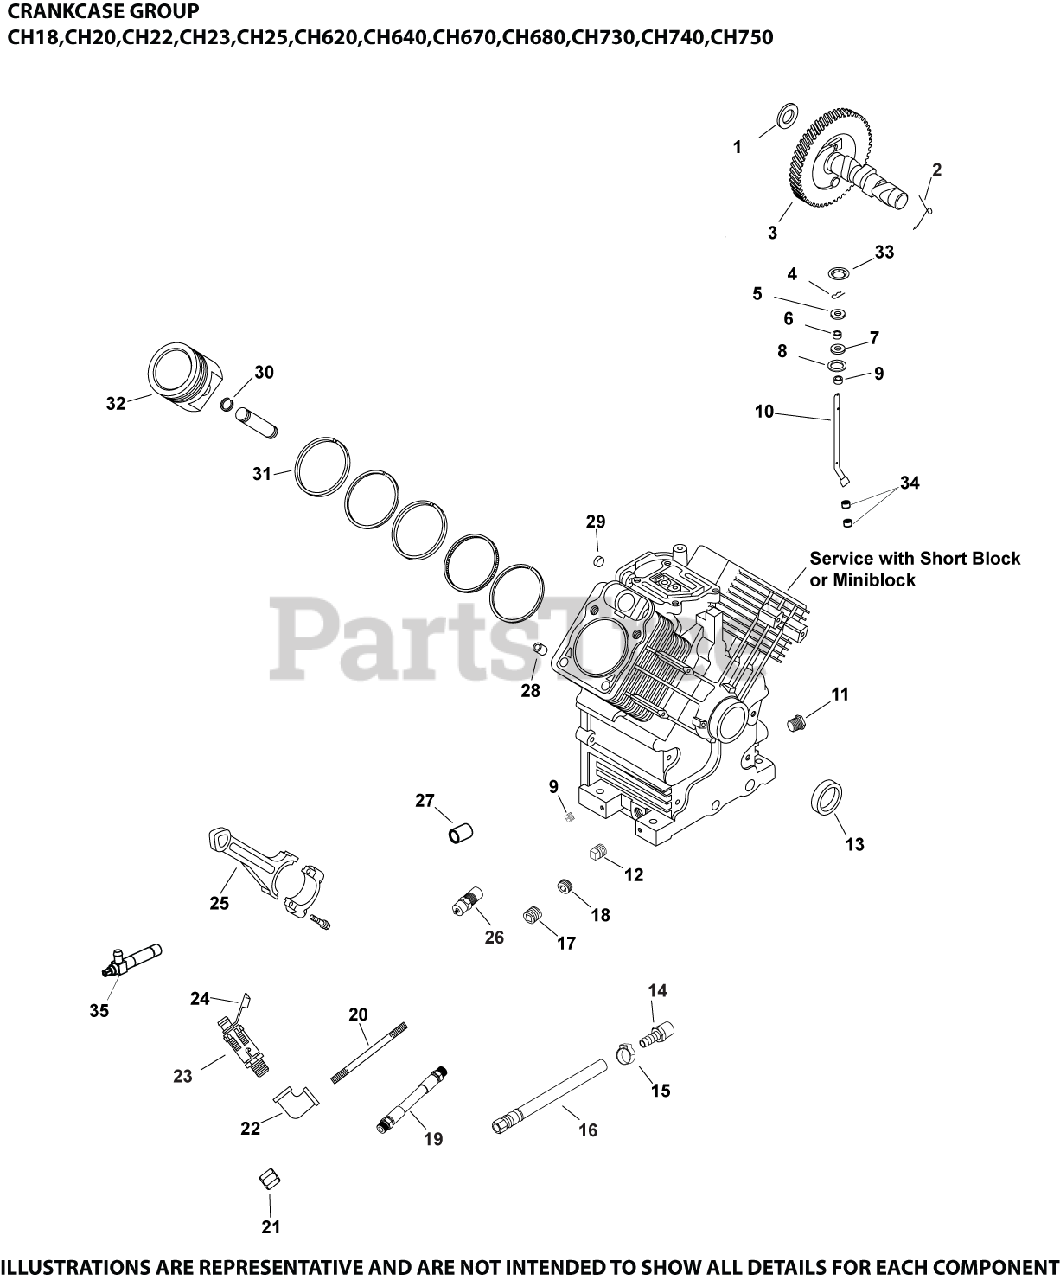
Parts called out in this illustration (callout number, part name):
3	KIT, CAMSHAFT
5	WASHER, FLAT 9 MM
7	SEAL, GOVERNOR CROSS SHAFT
10	SHAFT, GOVERNOR CROSS
12	PLUG, SQ HD PIPE 3/8"
13	SEAL, OIL (HELIX LIP)
25	ROD ASSY,CONNECTING USE 24 067 34-S
28	PIN, LOCATING
29	PLUG, CUP
30	RETAINER, PISTON PIN
31	RING SET(STD)STYLE B-1.2mm Tp RING THICK
31	RING SET(.08)STYLE B-1.2mm Tp RING THICK
31	RING SET(.25)STYLE B-1.2mm Tp RING THICK
31	RING SET(.50)STYLE B-1.2mm Tp RING THICK
32	KIT, PISTON USE 25 874 13-S
32	KIT, PISTON W/RING SET (.08)
32	KIT,PISTON W/RING (0.25) 83mm
32	KIT,PISTON W/RING (0.50) 83mm USE 25 874 17-S
33	RETAINER, RING
35	VALVE, OIL DRAIN MEDIUM
